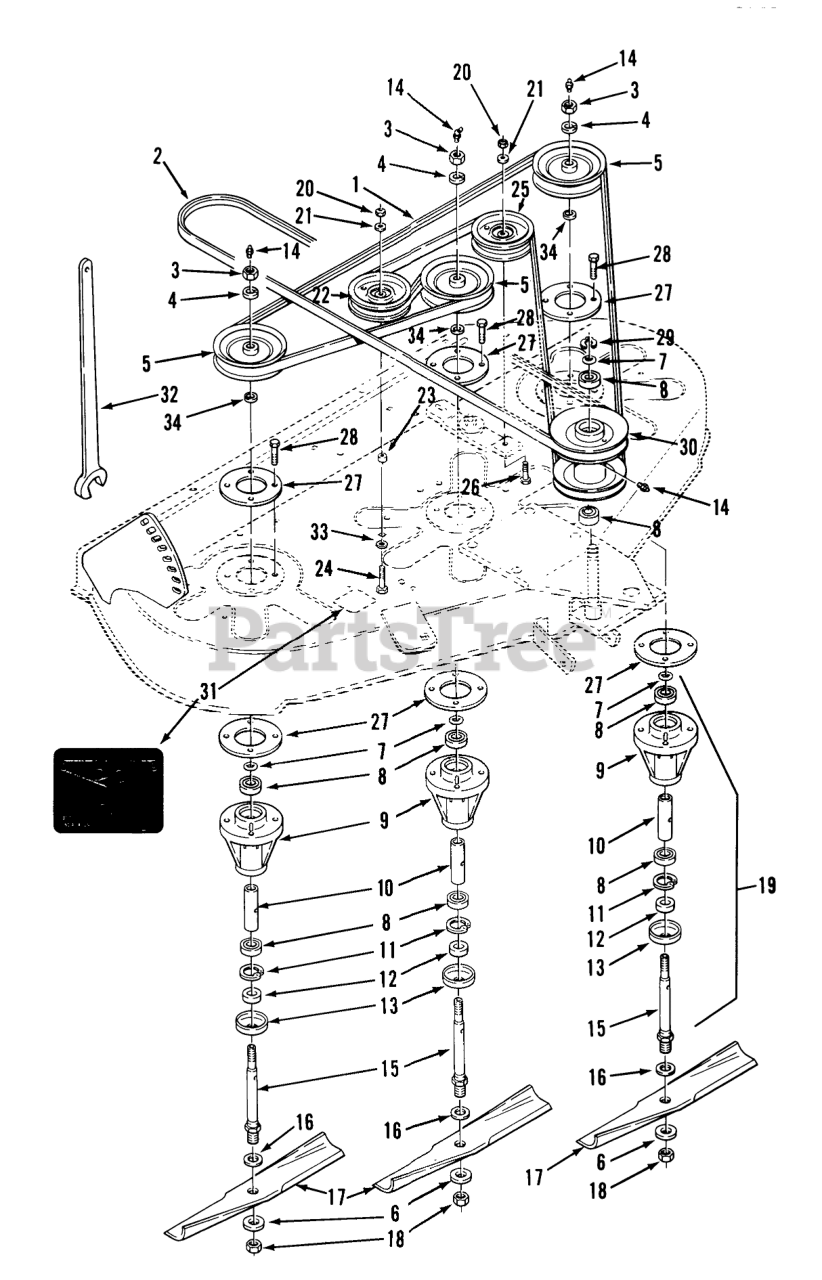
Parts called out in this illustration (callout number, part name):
1	V-BELT
2	V-BELT
3	Nut
4	Lockwasher
5	Pulley
6	Washer
7	O RING
8	BEARING-BALL
9	HOUSING-SPINDLE
11	Ring-Snap
12	SPACER-BLADE
13	CUP-SPINDLE
14	Zerk
14	FITTING-GREASE
15	SHAFT-SPINDLE
16	Washer
17	BLADE KIT
17	SERV ASS'Y-BLADE PKG
18	Nut
19	Spindle Assembly
20	NUT
21	Washer
22	Pulley-Idler
23	SPACER
24	Bolt
25	PULLEY-FLAT IDLER
26	BOLT
27	SPACER-SPINDLE
28	Bolt
29	RETAINING RING
30	PULLEY-COUNTER SHAFT
31	DECAL-BELT INSTALL
32	Spindle Wrench
33	WASHER
34	Washer
